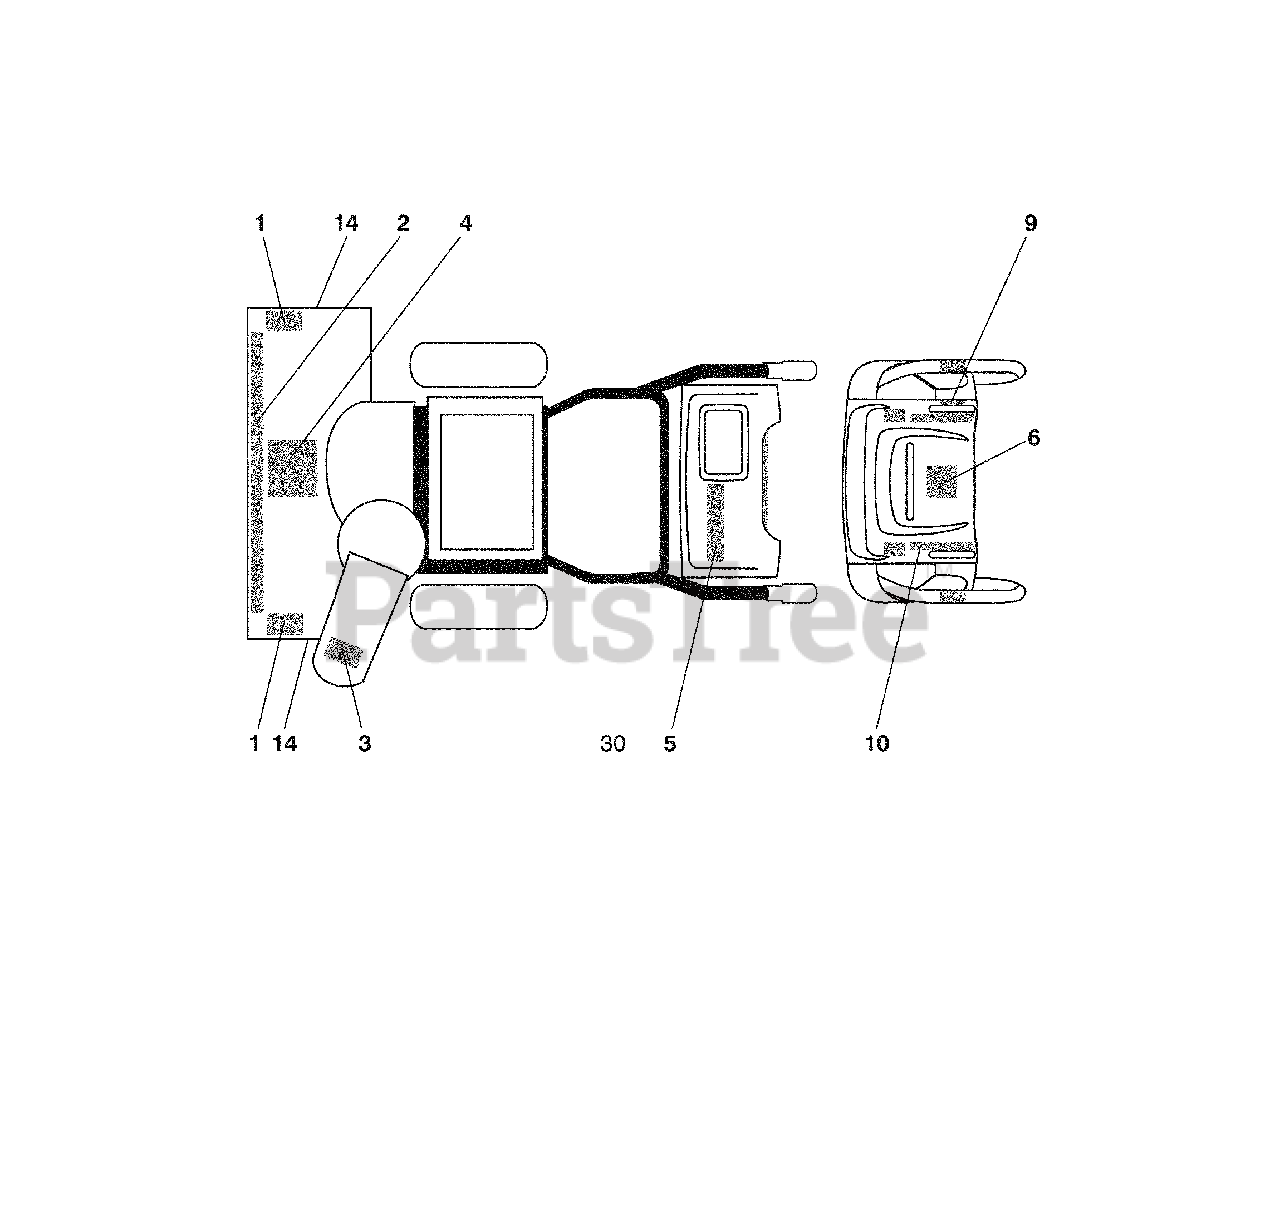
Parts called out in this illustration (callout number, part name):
1	Decal, Danger
2	Decal, Husqvarna
3	Decal, Danger, Deflector
4	Decal, Danger
5	Decal, Husqvarna, 1330SBE
6	Decal, Instruction
9	Decal, Speed Control
10	Decal, Remote Deflector
11	Decal, LH Trigger
12	Decal, RH Trigger
14	Decal, Husqvarna, Crown
